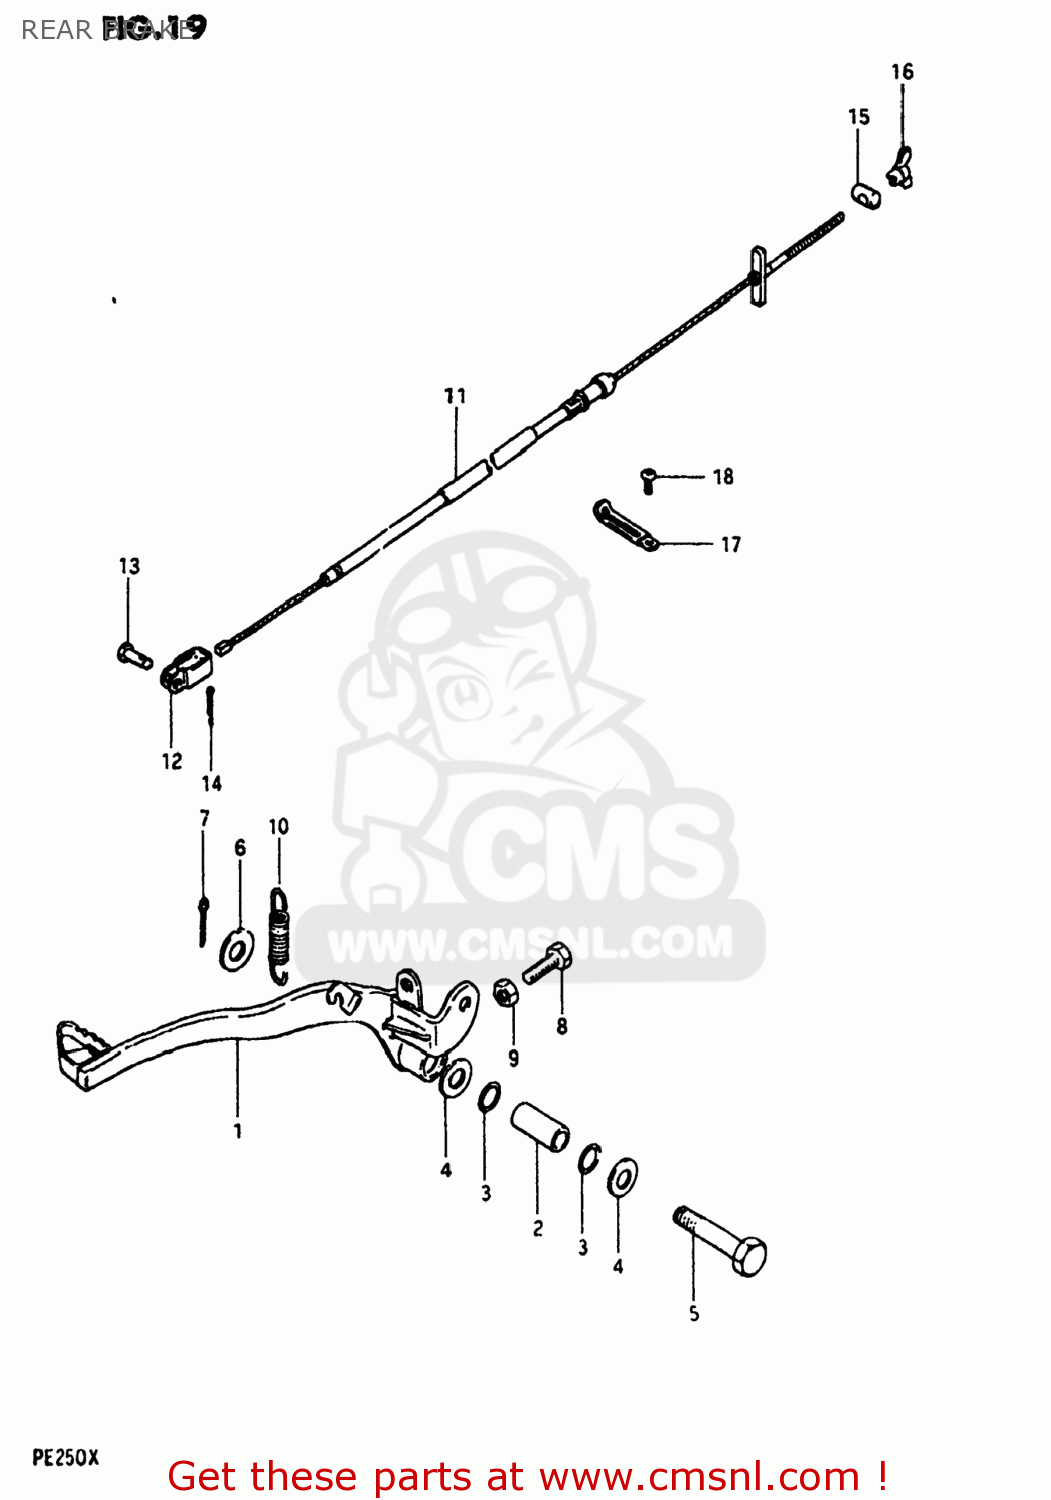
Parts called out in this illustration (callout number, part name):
1	PEDAL,BRAKE
2	SPACER (8X10X22)
3	O-RING (D:1.5 ID:10)
4	WASHER
5	BOLT 8X43.5
6	WASHER
7	PIN 20X20
8	BOLT 6X25
9	NUT
10	SPRING
11	CABLE,RR BRAKE
12	HOOK,REAR BRAKE PEDAL
13	PIN(L:13)
14	PIN
15	PIN
16	NUT
17	CLAMP
18	SCREW,6X6
